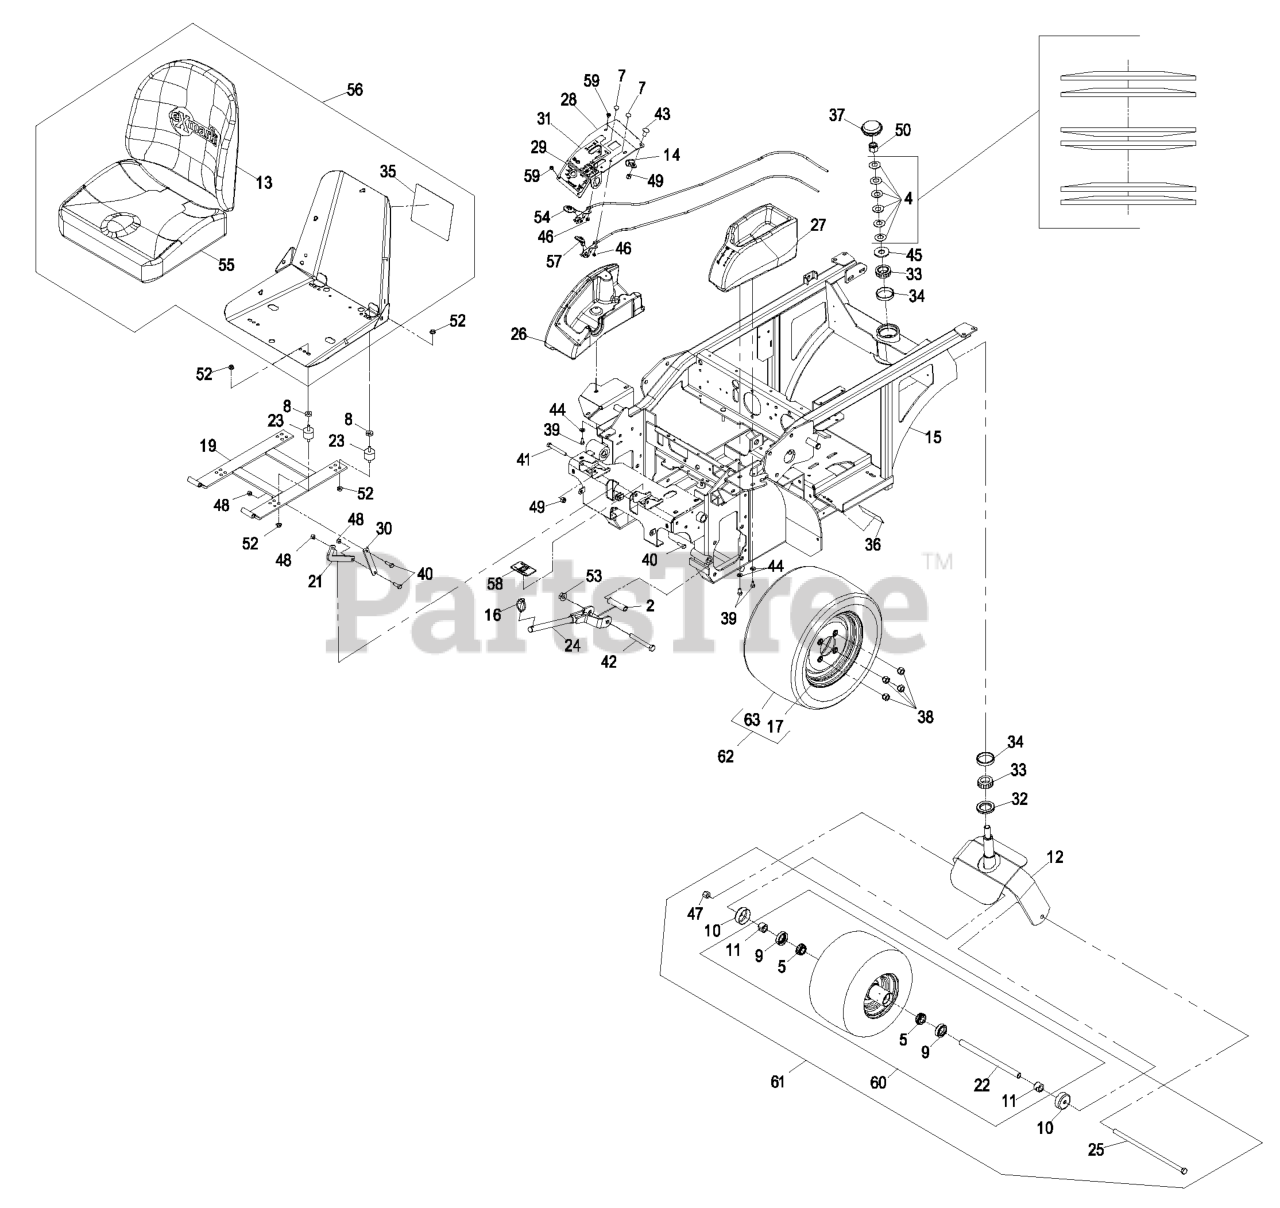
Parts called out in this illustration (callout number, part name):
2	SPACER-WHEEL, SHORT
4	WASHER-BELLVILLE
5	BEARING-CONE, TAPERED ROLLER
6	ASM,SEAT FRAME W/DECAL
7	BOLT-CARR
8	SPACER
9	SEAL-CASTER
10	GUARD-SEAL
11	SPACER-NUT
12	FORK-REAR CASTER
13	CUSHION,SEAT BACK
14	CLIP-LOOM
16	PIN-LYNCH
17	ASM,WHEEL
19	FRAME-SEAT
20	Plate-Hyd. Reservoir
21	LINK-SEAT STOP, LOWER
23	MOUNT-VIBRATION, RUBBER
24	Wld, Push Rod
25	SCREW-HH
29	DECAL,IGNITION/SPEED CONT
30	LINK-SEAT
31	DECAL,INSTRUMENT PANEL
32	SEAL-GREASE
33	BEARING-ROLLER, CONE TAPE
34	CUP-TAPERED, ROLLER BEARI
36	DECAL,CLUTCH ADJUSTMENT
37	CAP-GREASE
38	NUT-LUG
39	SCREW-HH
40	SCREW-HH
41	SCREW-CARR
42	SCREW-HH
43	SCREW-CARR
44	WASHER-PLAIN
45	WASHER-FLAT
46	NUT-LOCK, NI
47	NUT-LOCK, NI
48	NUT-LOCK, NI
49	NUT-LOCK, NI
50	NUT-LOCK, NI
53	NUT-HHF
54	CABLE-CHOKE
56	ASM,SEAT W/DECALS
57	CABLE-THROTTLE
58	DECAL,WHEEL MOTOR RELEASE
59	SCREW-PPH
60	ASM,WHEEL,TIRE & BRG SP
61	REAR CASTER WHEEL ASM
62	ASM,WHEEL & TIRE
